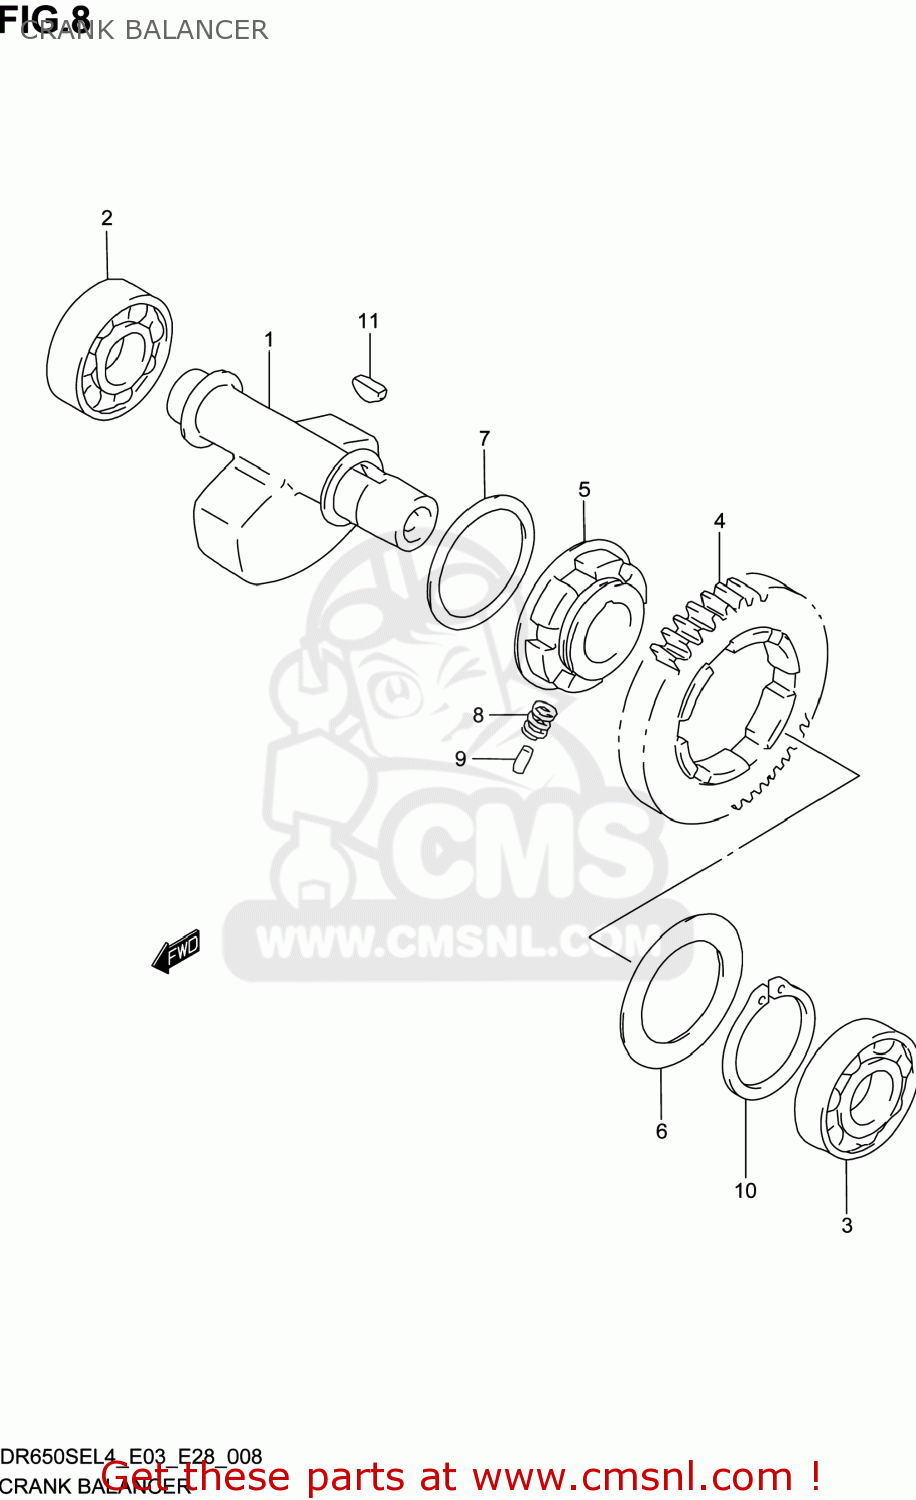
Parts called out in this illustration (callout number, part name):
1	BALANCER,CRANK
2	BEARING(22X56X16)
3	BEARING(20X47X14)
4	GEAR,CRANK BAL DRIVEN(NT:43)
5	RACE,CRK BAL DRIVEN GR INNER
6	WASHER
7	WASHER
8	SPRING
9	PIN(4.5X9.5)
10	CIRCLIP
11	KEY
